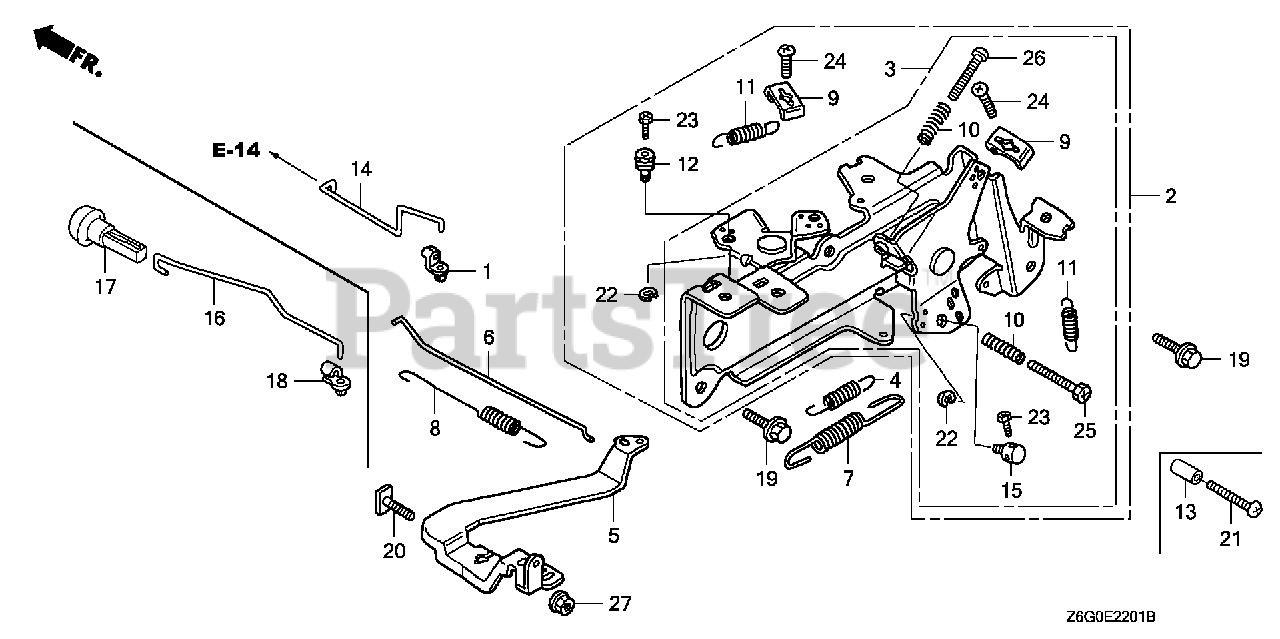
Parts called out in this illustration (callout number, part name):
1	JOINT, ROD
3	CONTROL ASSY.
4	SPRING, STARTER
5	ARM, GOVERNOR
6	ROD, GOVERNOR
7	SPRING, GOVERNOR
8	SPRING, THROTTLE RETURN
9	HOLDER, CABLE
10	SPRING, CONTROL ADJUSTING
11	SPRING, CABLE RETURN
13	COLLAR, STOPPER
14	ROD, CHOKE CONTROL
15	HOLDER, CABLE
16	ROD, CHOKE KNOB
17	KNOB, CHOKE
18	BUSH, LINKAGE
19	BOLT, FLANGE (6X14) (CT200)
20	BOLT, GOVERNOR ARM
21	SCREW, RECESSED (5X25)
22	CIRCLIP (5MM)
23	BOLT, RECESSED (4X6)
24	BOLT, RECESSED (5X16)
25	BOLT, RECESSED (5X25)
26	SCREW, PAN (5X25)
27	NUT, FLANGE (6MM)
